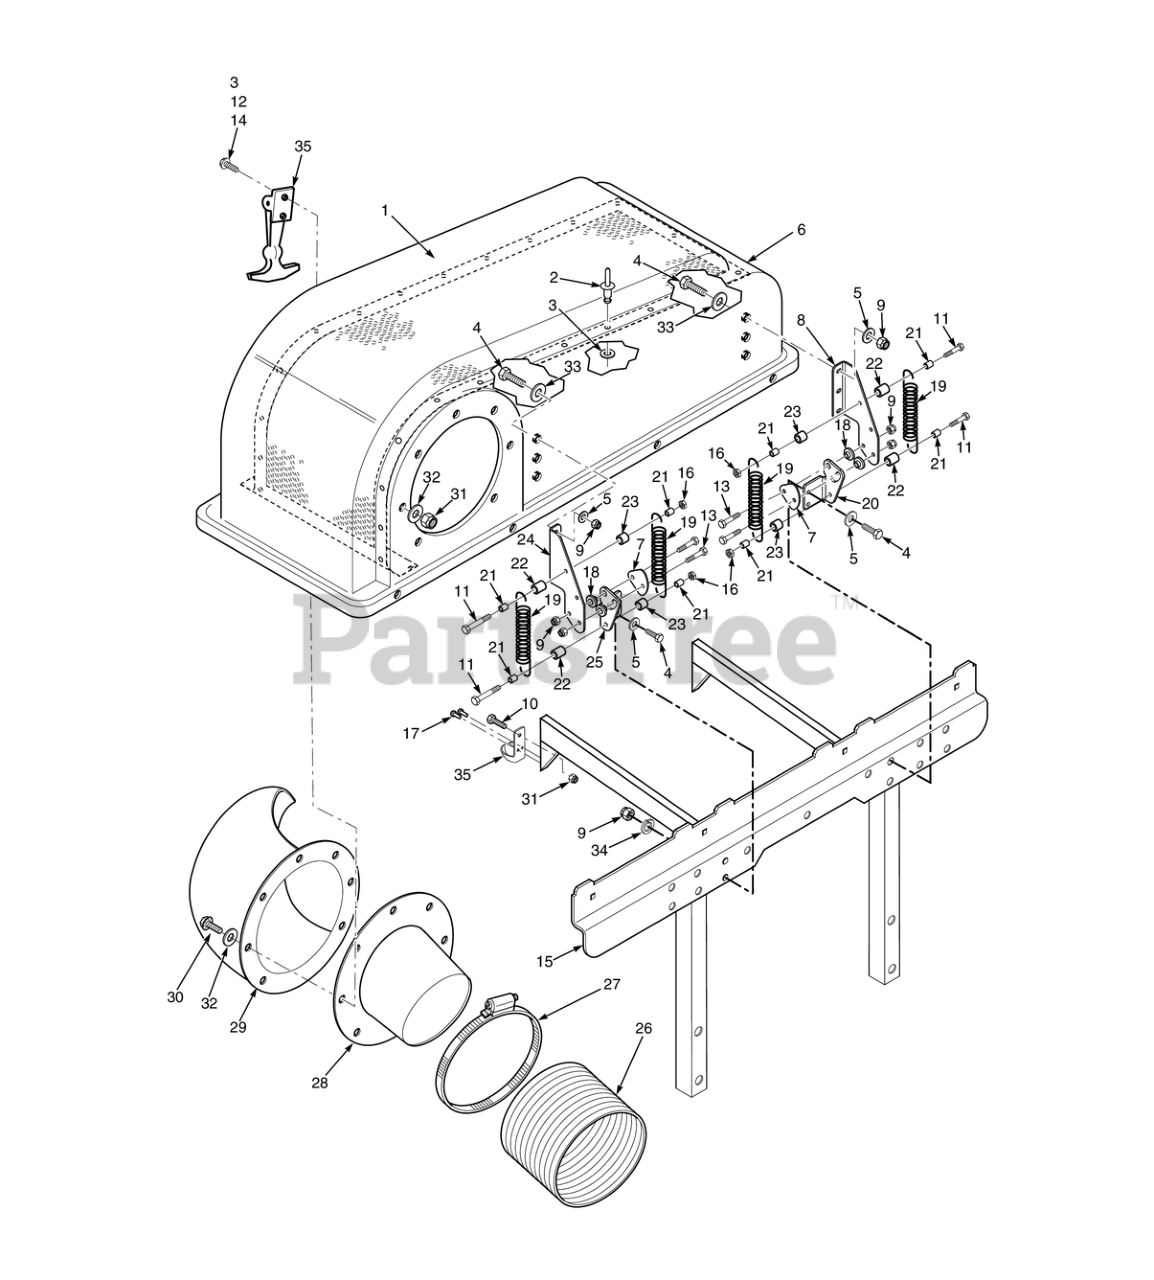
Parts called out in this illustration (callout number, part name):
1	Screen, Catcher Hood
2	Pop Rivet, 3/16 x .652"
3	Flatwasher, 3/16 (.196 x .469 x .048)
4	Bolt, Hex Head 3/8-16 x 1-1/4", Kawasaki FX / FS
5	Flatwasher, 3/8-.391 x .938 x .105
6	Hood Assembly, GC-STT
7	Guard, GC Hinge
8	Hinge, Upper LH
9	HEX NUT, ELASTIC STOP LOCK, 3/8-16
10	BOLT, SERRATED FLANGE HEX HEAD 5/16-18 X 3/4"
11	Bolt, Hex Head 3/8-16 x 4.00
12	HEX NUT, ELASTIC STOP LOCK # 10-32
13	Bolt, Hex Head, 3/8-16 x 1-1/2"
14	Screw, #10-32 x 3/4"
15	Support Weldment, Bag Frame
16	Bolt, Hex Head 3/8-16 x 1" Ser. Flg.
17	Rivot, 3/16 x .402 POP
18	Bushing, Hopper Pivot
19	Spring, Hood Hinge
20	HINGE, LOWER LH
21	Spacer, Deck Assist
22	Spacer
23	SPACER, J-PULL ROD
24	Hinge, Upper RH
25	HINGE, LOWER RH
26	Hose, 8.00" Dia. x 53" Long
27	Clamp, 8-5/8" Max Dia. (61")
28	Tube, Filler (8" Hose)
29	Elbow (8" Hose)
30	Bolt, 5/16 - 18 x 1 - 1/4" Hex Head
31	HEX NUT, ELASTIC STOP LOCK, 5/16-18
32	Flatwasher, 5/16-.375 x .875 x .083 (35BV & 37BV-EFI)
33	Flatwasher, 3/8-.406 x 1-1-1/2 x 7 Gauge
34	Lockwasher, 3/8" Spring, Kawasaki FX / FS
35	Latch, Hopper
